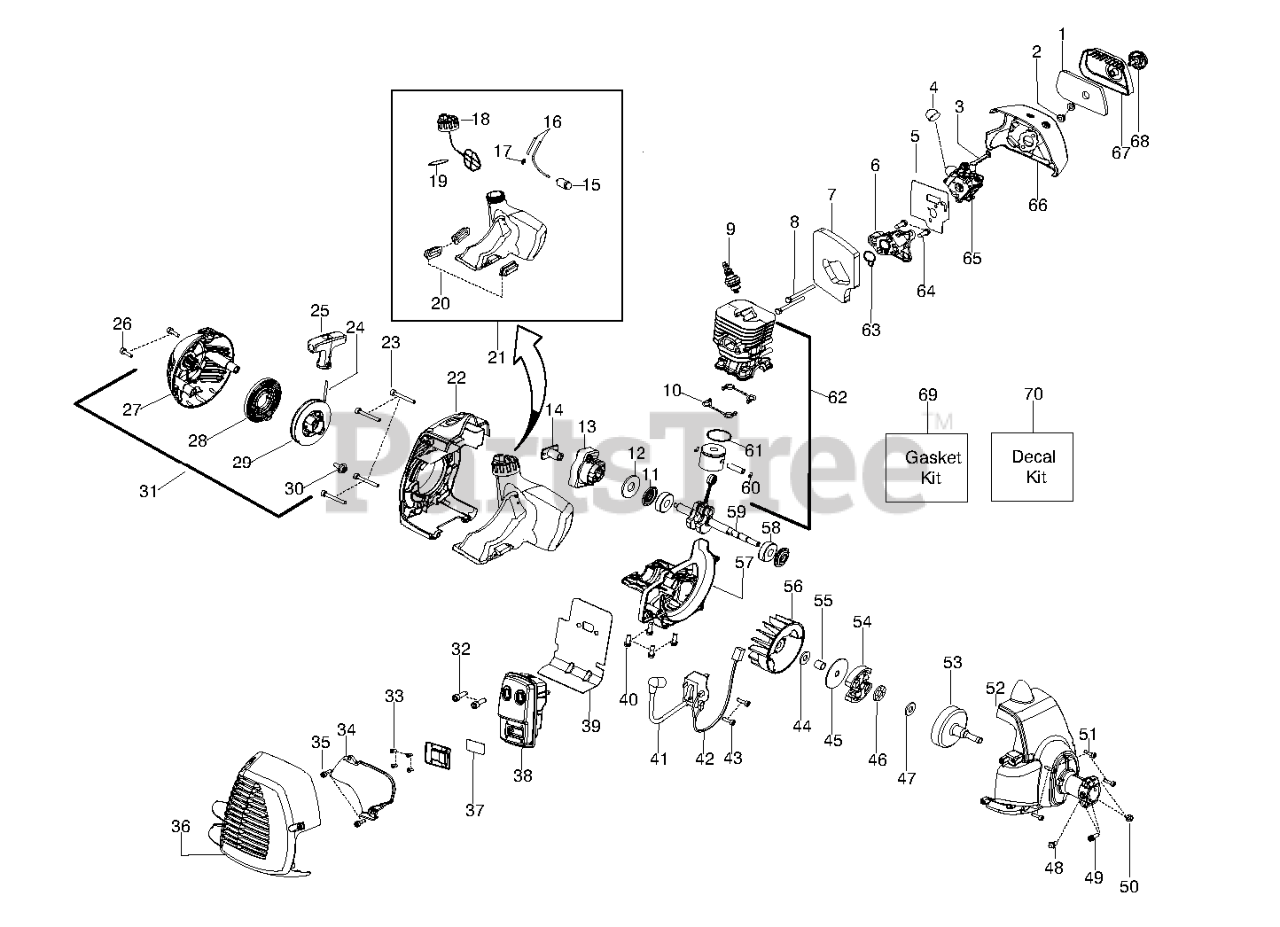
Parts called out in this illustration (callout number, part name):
1	FILTER AIRBOX
3	CHOKE LEVER
4	PURGE BULB ZAMA
5	KIT GASKET CARB 28CC
6	CARB ADAPTOR
7	KIT GASKET 28CC
8	BOLT CARB ADAPTOR
9	Plug - Spark (RCJ-8Y)
10	KIT GASKET 28CC
11	KIT GASKET 28CC
12	WASHER FLAT
13	ASSY STARTER CUP
14	COUPLING-STARTER
15	FUEL PICK-UP ASSY
16	KIT-LINE(FUEL)
17	FUEL LINE FITTING
18	ASSY-CAP W/RETAINER
19	KIT GASKET 28CC
20	ISOLATOR FUEL TANK
21	KIT FUEL TANK HVA
22	REAR SHROUD ORANGE
25	STARTER HANDLE GRAY
26	SCREW M5-0.8X30MM
27	STARTER HOUSING
28	%KIT STARTER SPRING
29	KIT STARTER PULLEY
31	ASSY-STARTER HSG.
32	BOLT MUFFLER
33	SCREW-6-19X5/16PLAST PA
34	SHIELD HEAT
35	SCREW M4 X 1.75 PT 16MM
36	KIT MUFFLER GUARD HVA
37	KIT SPARK ARRESTOR SCREEN
38	KIT MUFFLER LE28 NON CAT
39	KIT GASKET 28CC
40	SCREW-M5-0.8 X 25MM(TAP)
41	IGNITION MODULE MBU-7
42	ASSY MODULE LEAD WIRE
43	SCREW M4 X .70 TT 16MM
44	WASHER CLUTCH
45	WASHER-CLUTCH
46	BEARING THRUST
47	WASHER THRUST
48	SCREW-10-14 X 1/2 PLASTITE
49	SCREW-10-24 X 1" (UNC)
50	LOCKNUT-HEX 10-24
51	SCREW M4 X .70 TT 16MM
52	ASSY FAN HOUSING HVA 1"
53	ASSY-CLUTCH DRUM
54	ASSEMBLY CLUTCH
55	SPACER FLYWHEEL
57	CRANKCASE CAST LE28
58	BEARING RADIAL BALL (6201)
59	ASSY CRANKSHAFT 28CC
60	WRIST PIN RET.
61	RING PISTON
62	KIT PISTON & CYLINDER
63	KIT GASKET 28CC
64	SCREW-M5-0.8 X 25MM(TAP)
65	CARBURETOR KIT W41
66	RP_AIR BOX
67	COVER-AIR BOX
68	KNOB ASSY AIRBOX COVER
69	KIT GASKET 28CC
